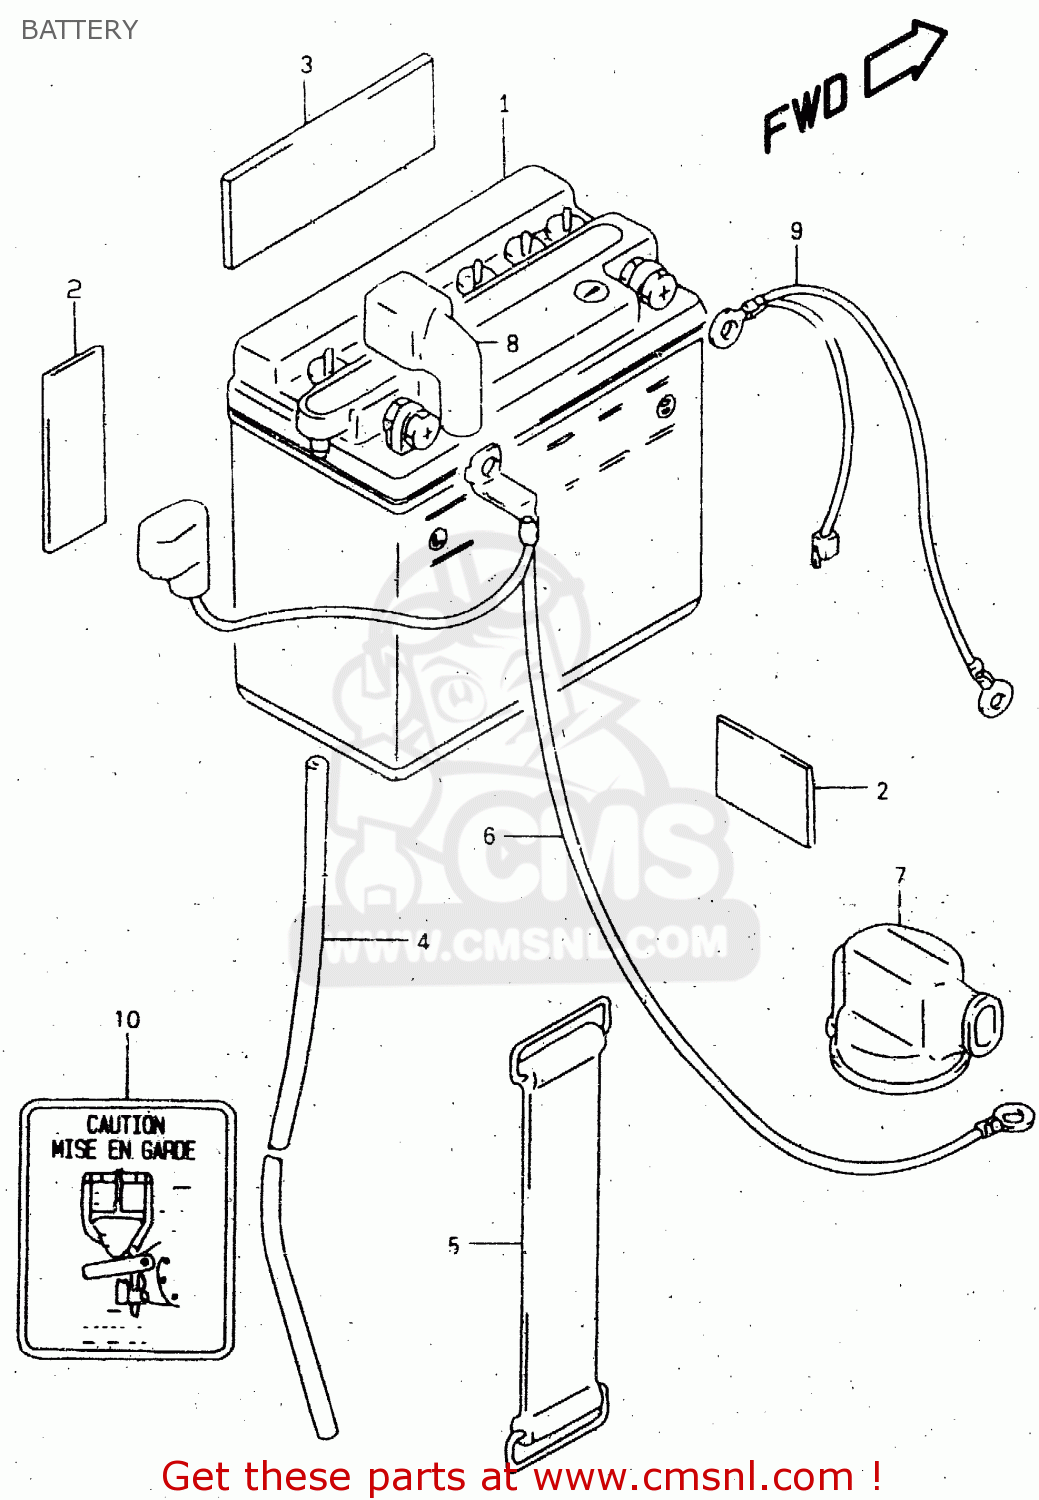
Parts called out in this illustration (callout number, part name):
1	BATTERY ASSY(YB7-A)
2	PROTECTOR(170X95X3.0)
3	CUSHION 20X45X6
4	HOSE,BATTERY EXHAUST(L:780)
5	BAND
6	WIRE,BATTERY PLUS LEAD
7	CAP,STARTER RELAY
8	CAP,BATTERY PLUS TERMINAL
9	WIRE,BATTERY MINUS LEAD
10	PLATE,BATTERY CAUTION
